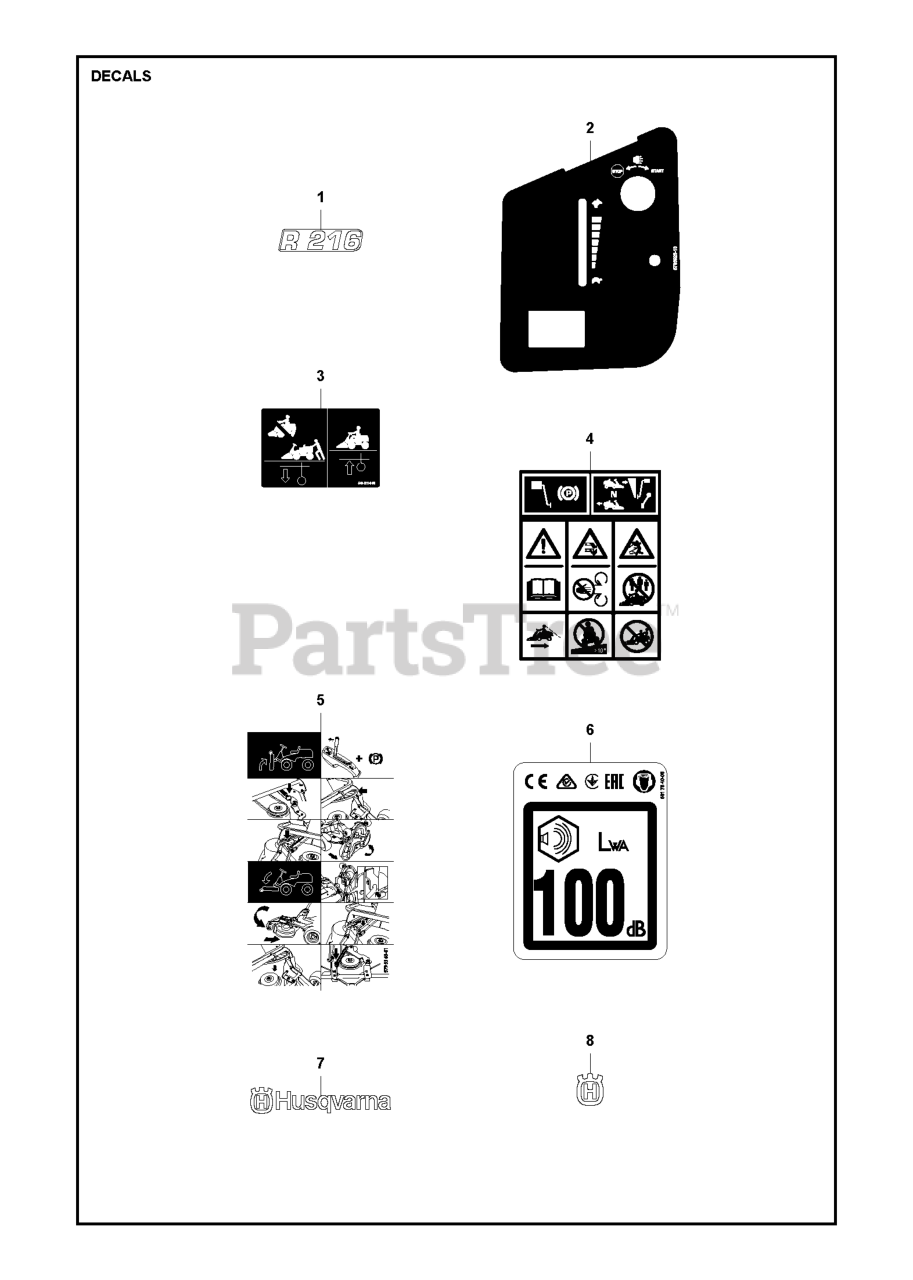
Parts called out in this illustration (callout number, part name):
2	MUFFLER.ASM.SNGL.XTNDED.DFLCTR
9	KEEPER.BELT.ENGINE.4.2
12	RP_PULLEY ENGINE
15	TANK.ASM.FRT.2.5 GAL.W/CAP.EPA
18	CAP.FUEL.2 WAY VENT
20	CONTROL.TH/CK.COBRA.KO
21	SCREW.#10 X 0.750.BOS
28	LINE.FUEL.20"FRONT.EMI
29	KIT.SPARK ARRESTOR 794945 B&S
37	HOSE CLAMP
42	LOCKWASHER
45	NUT
69	GASKET.EXHAUST.KOHLER
79	SCREW.SOCKET HD.5/16-1
81	TUBE, DRAIN OIL ASM.
82	VALUE.OIL.DRAIN
85	BOLT HEX 7/16-20X4-1/4"
87	BOLT 5/1618UNC X 3/4 W/ SEMS
90	SCREW 3/8-16X1
92	SCREW 3/8-16X1
94	RP.TUBE.EXHAUST.KOHL.COURAGE
97	SCREW HEXWSHR 1/4-20X3/4
138	RP PURGE LINE
